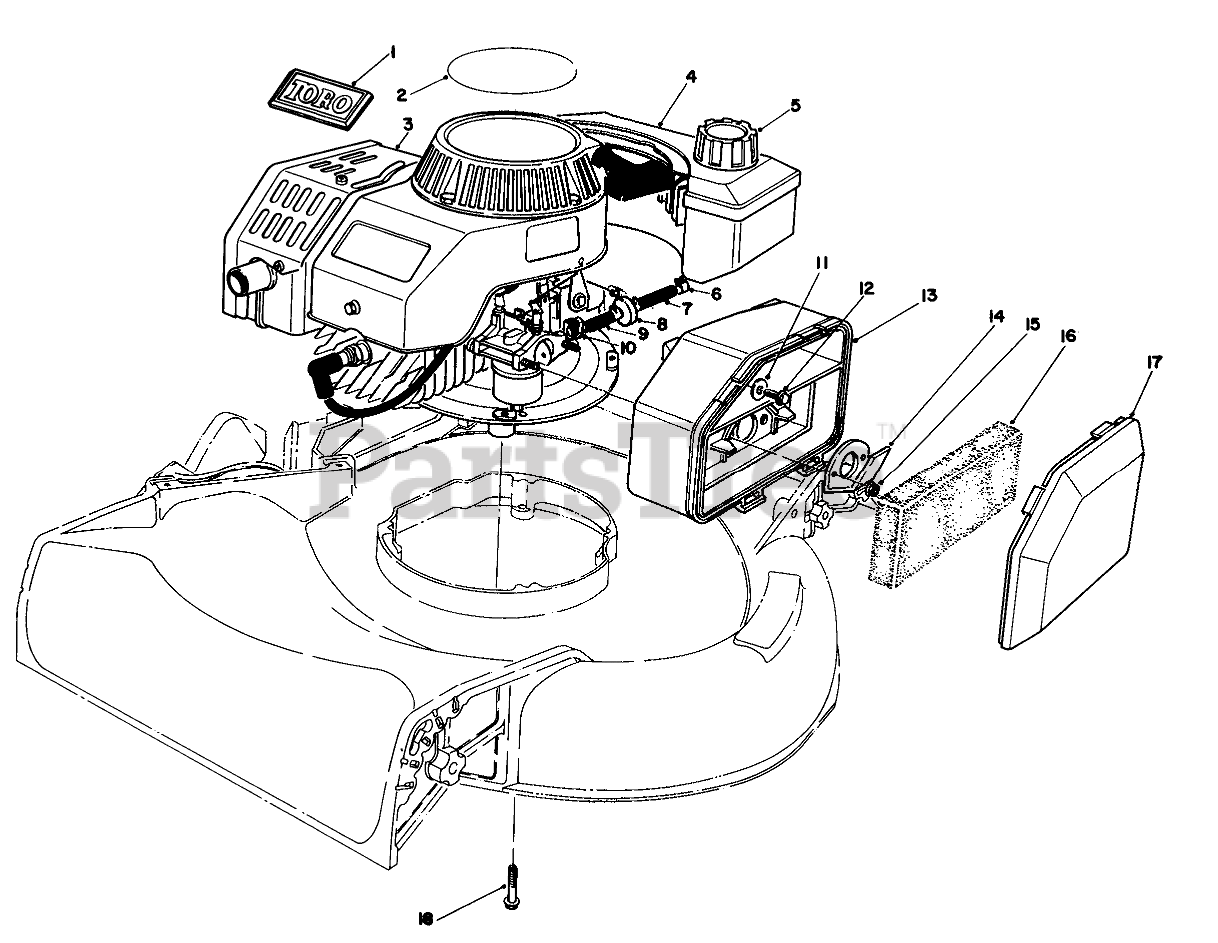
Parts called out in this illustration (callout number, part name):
1	TORO LOGO PLT
1	Handle-Upper
2	DECAL- 2 CYC RECOIL
2	Control-Panel (Incl. Ref. #3)
3	Engine (Complete)
3	Decal-Instruction
4	FUEL TANK ASM
4	THROTTLE CONT-SERVICE
5	GAS CAP ASM
5	Decal-Toro
6	CLAMP-FUEL LINE
6	SCREW-HWHTF
7	HOSE-FUEL
8	FILTER-FUEL
8	LOWER HANDLE ASM
9	HOSE-FUEL
9	PIN-COTTER, HAIR
10	FUEL LINE CLAMP
10	NUT-LOCK, NI
11	WASHER-FLAT
11	HANDLE PIN
12	SCREW-HH
13	AIR CLEANER
13	5/16-18 X 2 HNDLE SCREW
14	SPIT BACK DEFLECTOR
15	NUT-LOCK
16	FILTER
17	AIR CLEANER COVER
18	FLG SCREW,3/8-16X2.000
